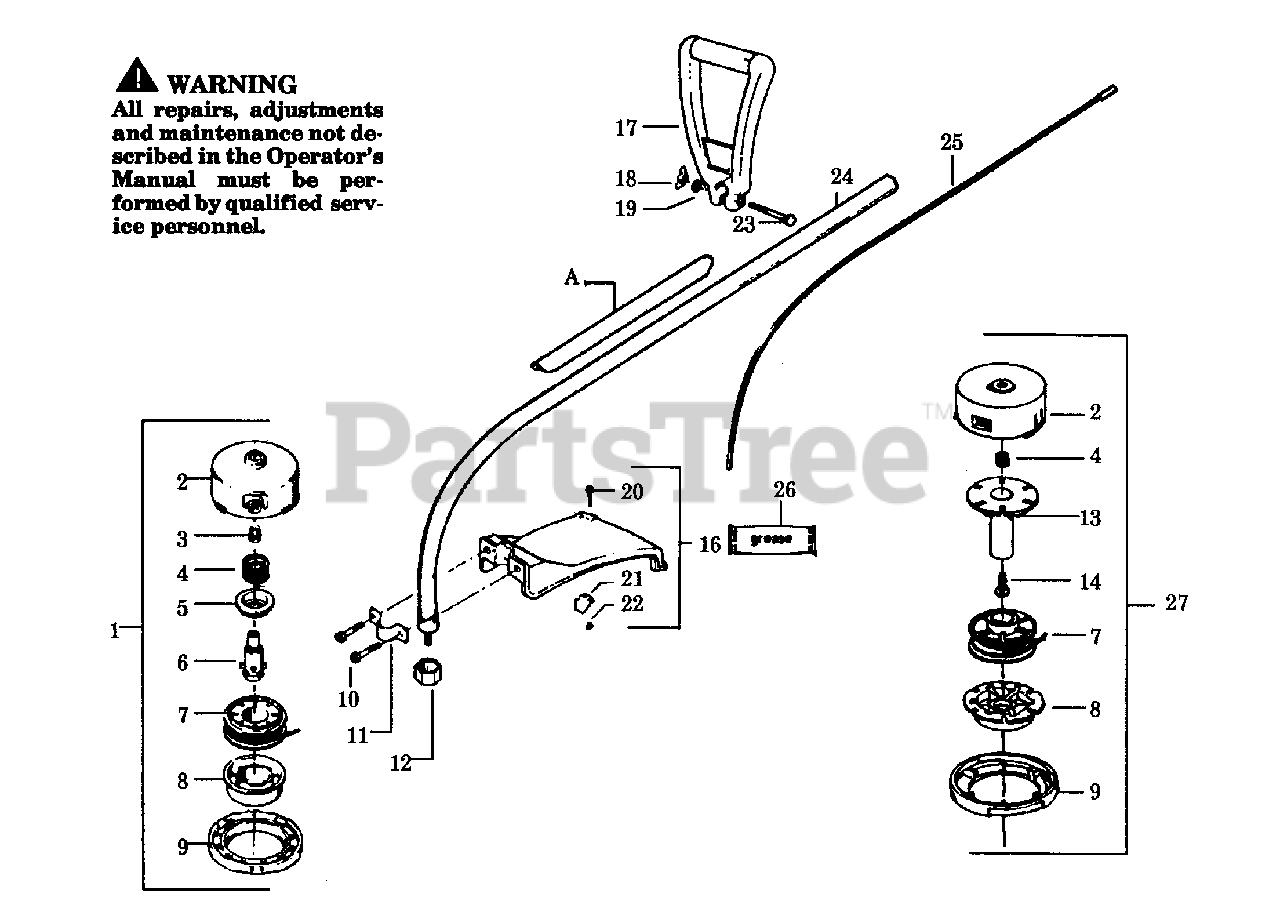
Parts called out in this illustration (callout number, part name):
1	Cutting Head Ass'y. (Inc.2-9) - See Service Ref. 5.
2	Model 1600 G.TRIMMER
2	Model 1600T
3	Line Saver (Model 1600 G.TRIMMER Only)
4	Model 1600 G.TRIMMER
4	Model 1600T
5	Spring Adaptor-Model 1600 G.TRIMMER Only
6	Drive Gear-Model 1600 G.TRIMMER Only
7	Model 1600 G.TRIMMER
7	Model 1600T
8	Model 1600 G.TRIMMER
8	Model 1600T
9	Model 1600 G.TRIMMER
9	Model 1600T
10	Model 1600T
11	Shield Bracket
12	Dust Cup
13	Spool Post
14	Screw #10-24x5/8
16	Model 1600T
17	Assist Handle
18	Wing Nut
20	Screw #10-24xl
21	Model 1600 G.TRIMMER
21	Model 1600T
22	Nut
24	Model 1600 G.TRIMMER-T1
24	Model 1600 G.TRIMMER-T2,3 Model 1600T-T1
25	Model 1600 G.TRIMMER-T1
25	Model 1600 G.TRIMMER-T2,3 Model 1600T-T1
26	Flex Shaft Lube
27	Cutting Head Ass'y.(Inc.2,4,7,8,9,13,14) - See Service Ref. 5.
A	Safety Label Decal
